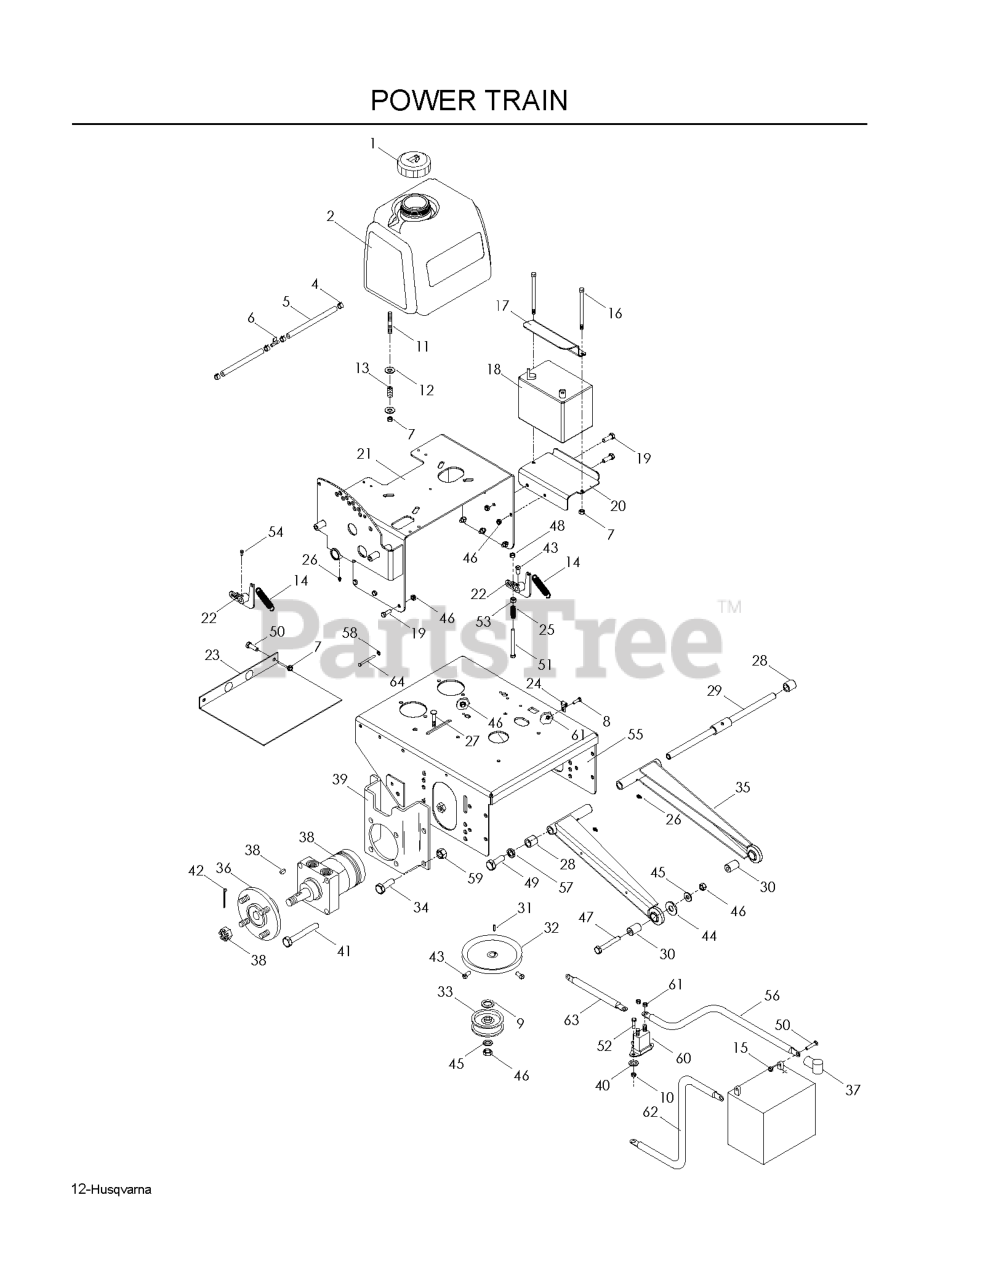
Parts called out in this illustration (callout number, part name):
1	FUEL CAP ANTI-SPLASH
3	JAM NUT 1/4C (2 2 PW01)
4	HOSE CLAMP
5	GAS LINE 10"
6	FUEL VALVE
7	NUT 5/16 NYLOC
8	HCS 1/4C X 3/4 HCS
9	WASHER, 3/8 SPEC
10	NUT 1/4C CENTER LOCK
11	STUD, 5/16C
12	WASHER 5/16 FLAT
14	SPRING-TRANS
15	NUT 5/16C CENTERLOCK
16	BOLT - 5/16 X 7
17	BATTERY STRAP
18	BATTERY, 12 V 330 AMP
19	SCREW 3/8C X 3/4 HEX CAP
20	BATTERY TRAY
21	TANK SUPPORT
22	PUMP ARM WELDMENT
23	LOWER BELT SHIELD
24	DOUBLE TUBE CLAMP
26	ZERK
27	RHSNB 3/8C X 2
29	STRUT SHAFT
30	FRONT SPACER
31	KEY 5 MM SQ X 25 MM
33	IDLER PULLEY
34	HCS 1/2C X 1 1/4 SERRATED HEAD
35	STRUT WELDMENT
36	HUB.WHEEL.ZTR
38	WHEEL MOTOR
39	MOTOR MOUNT
40	WASHER 1/4 INT TOOTH
41	HCS 1/2C X 2 3/4
42	COTTER PIN
43	SCREW 5/16C X 5/8 SQ HEAD
44	WASHER 1/2 FLAT
45	WASHER 3/8 FLAT
46	NUT 3/8C CENTERBLOCK
47	HCS 3/8C X 2 1/4
48	NUT 3/8-16 NYLOC
49	HHCS 1/2-13 X 1
50	HCS 5/16C X 3/4
51	HEX SCREW 3/8-20 X 2.75
52	HCS 1/4C X 5/8
54	5/16C X 5/8 "V" POINT
56	CABLE POSITIVE, LONG
57	WASHER 1/2" SPLIT LOCK
59	NUT 1/2-13 HEX NYLOC ZD
61	NUT.1/4-20.HEX.NYLOC.ZD
62	CABLE-NEGATIVE
63	CABLE POSITIVE, LONG
64	CLEVIS PIN
